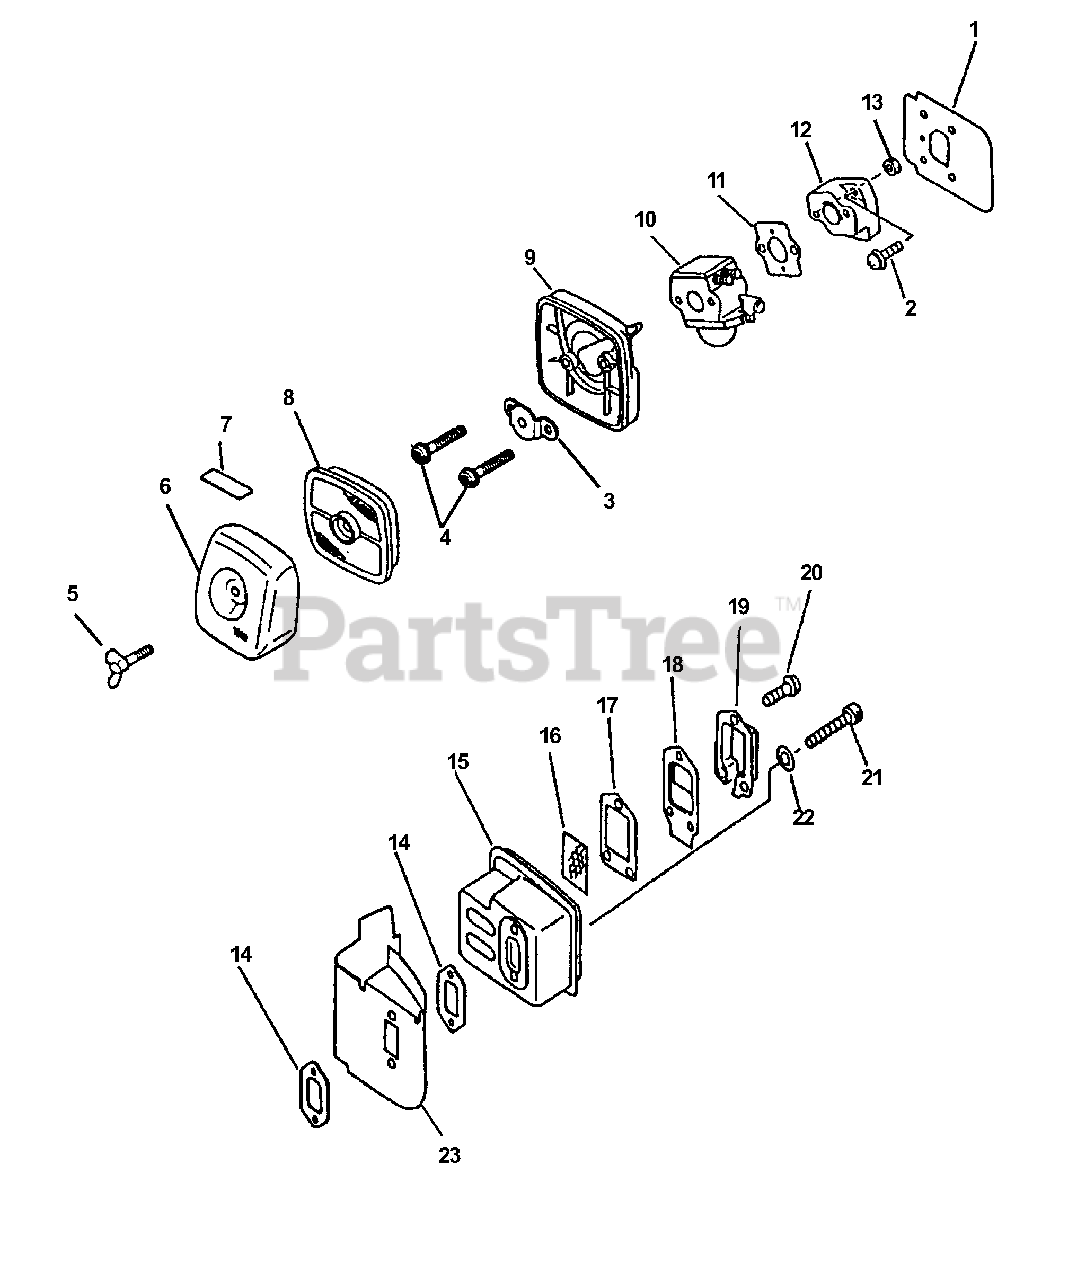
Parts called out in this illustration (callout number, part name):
1	SHIELD, INTAKE
2	SCREW - 5X20
3	PLATE, PREVENT
4	SCREW - 5X65
5	THUMBSCREW
6	COVER, AIR FILTER - GRAY
7	LABEL - CHOKE
8	FILTER, AIR
8	FILTER, AIR - SINGLE LAYER
9	AIR FILTER CASE ASSY
10	CARBURETOR C1U-K51
11	GASKET, INTAKE
12	INSULATOR, INTAKE
14	GASKET, EXHAUST
16	SCREEN, SPARK ARRESTOR
17	GASKET, EXHAUST
18	GASKET, EXHAUST - INNER
19	GUIDE, EXHAUST - OUTER
20	SCREW - 4X10
21	SCREW - 5X55
22	WASHER - 5
23	COVER, EXHAUST
